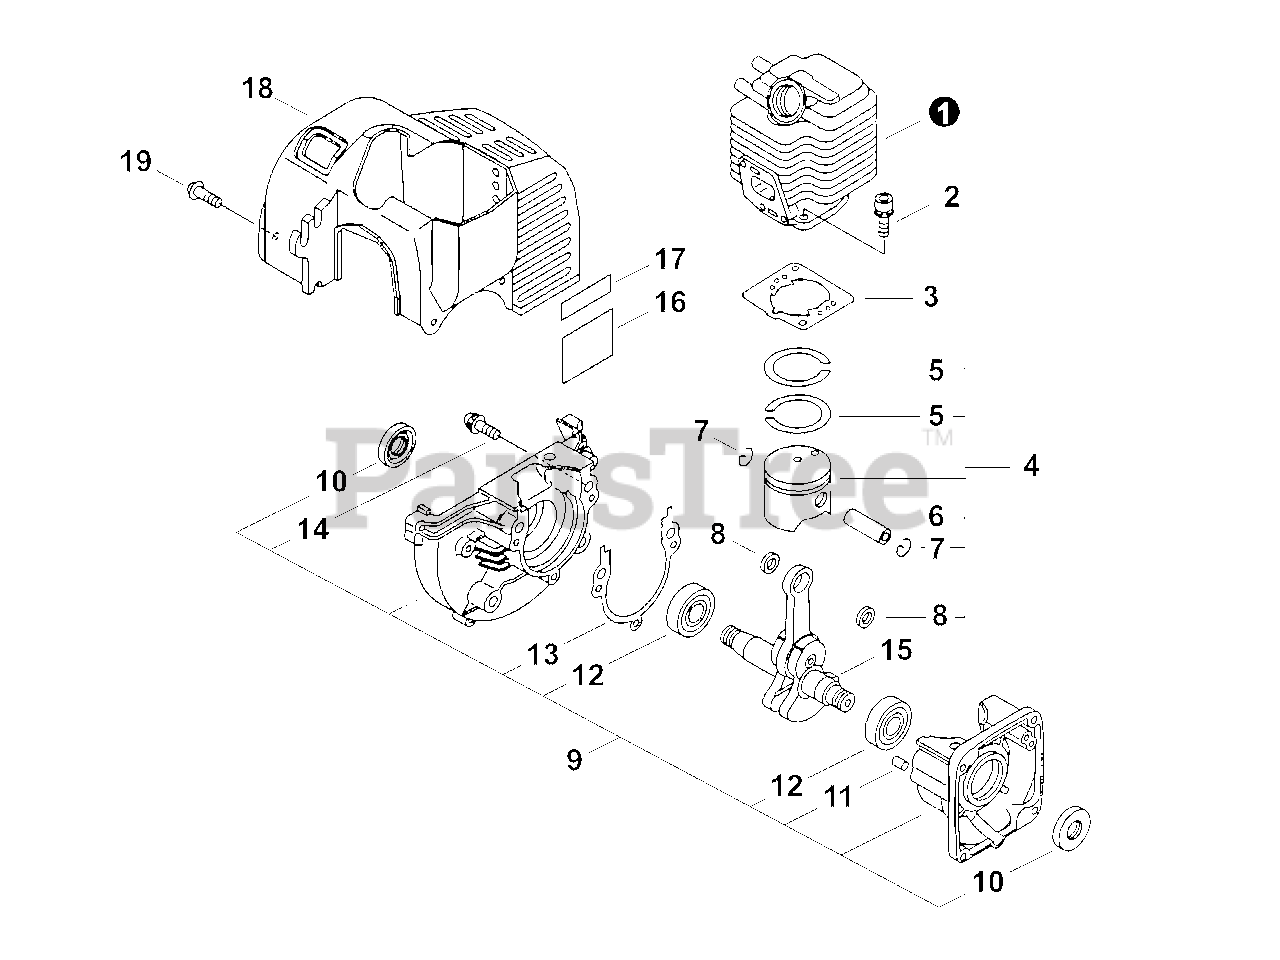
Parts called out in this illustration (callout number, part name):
1	CYLINDER
2	SCREW - 5×22
3	GASKET, CYLINDER
4	PISTON KIT
5	RING, PISTON
6	PIN, PISTON
7	RING, RETAINING
8	SPACER, PISTON
9	CRANKCASE KIT
10	SEAL, OIL
11	PIN, DOWEL
12	BEARING, BALL - 6201
13	GASKET, CRANKCASE
14	SCREW - 5×28
15	CRANKSHAFT ASY
16	LABEL - CAUTION
17	LABEL - MODEL -- EDR-210
18	COVER, ENGINE
19	SCREW - 4×12
